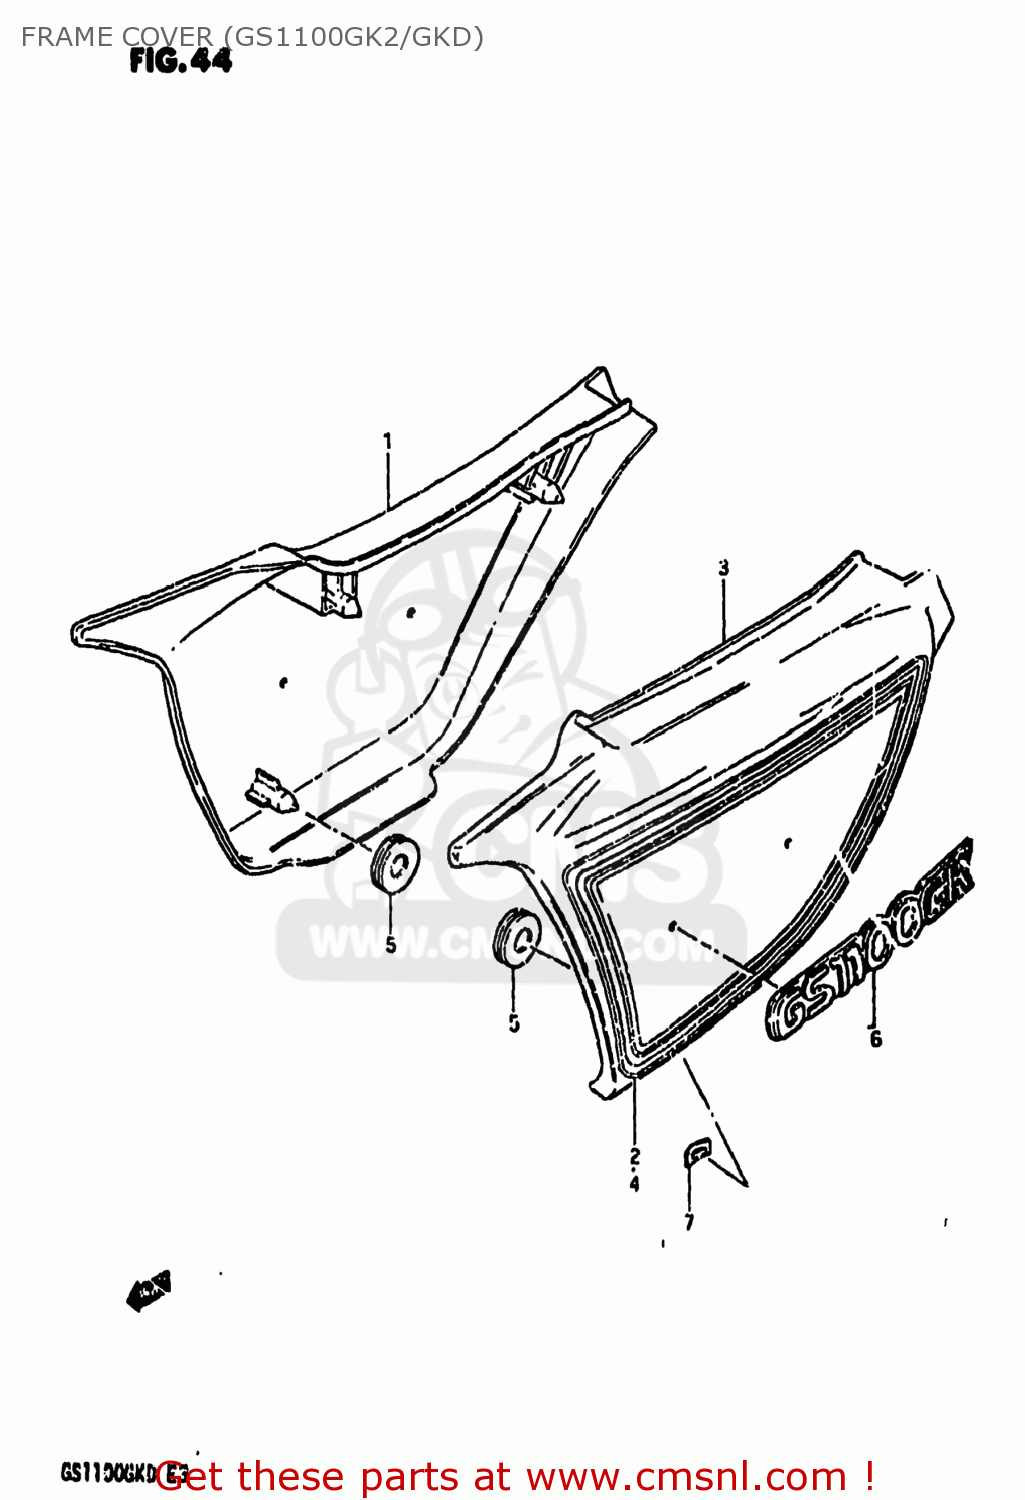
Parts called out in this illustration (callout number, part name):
1	COVER,FRAME,RIGHT
2	TAPE SET,FRAME COVER
3	COVER,FRAME,LEFT
4	TAPE SET,FRAME COVER
5	CUSHION
6	EMBLEM,FRAME COVER
7	NUT
